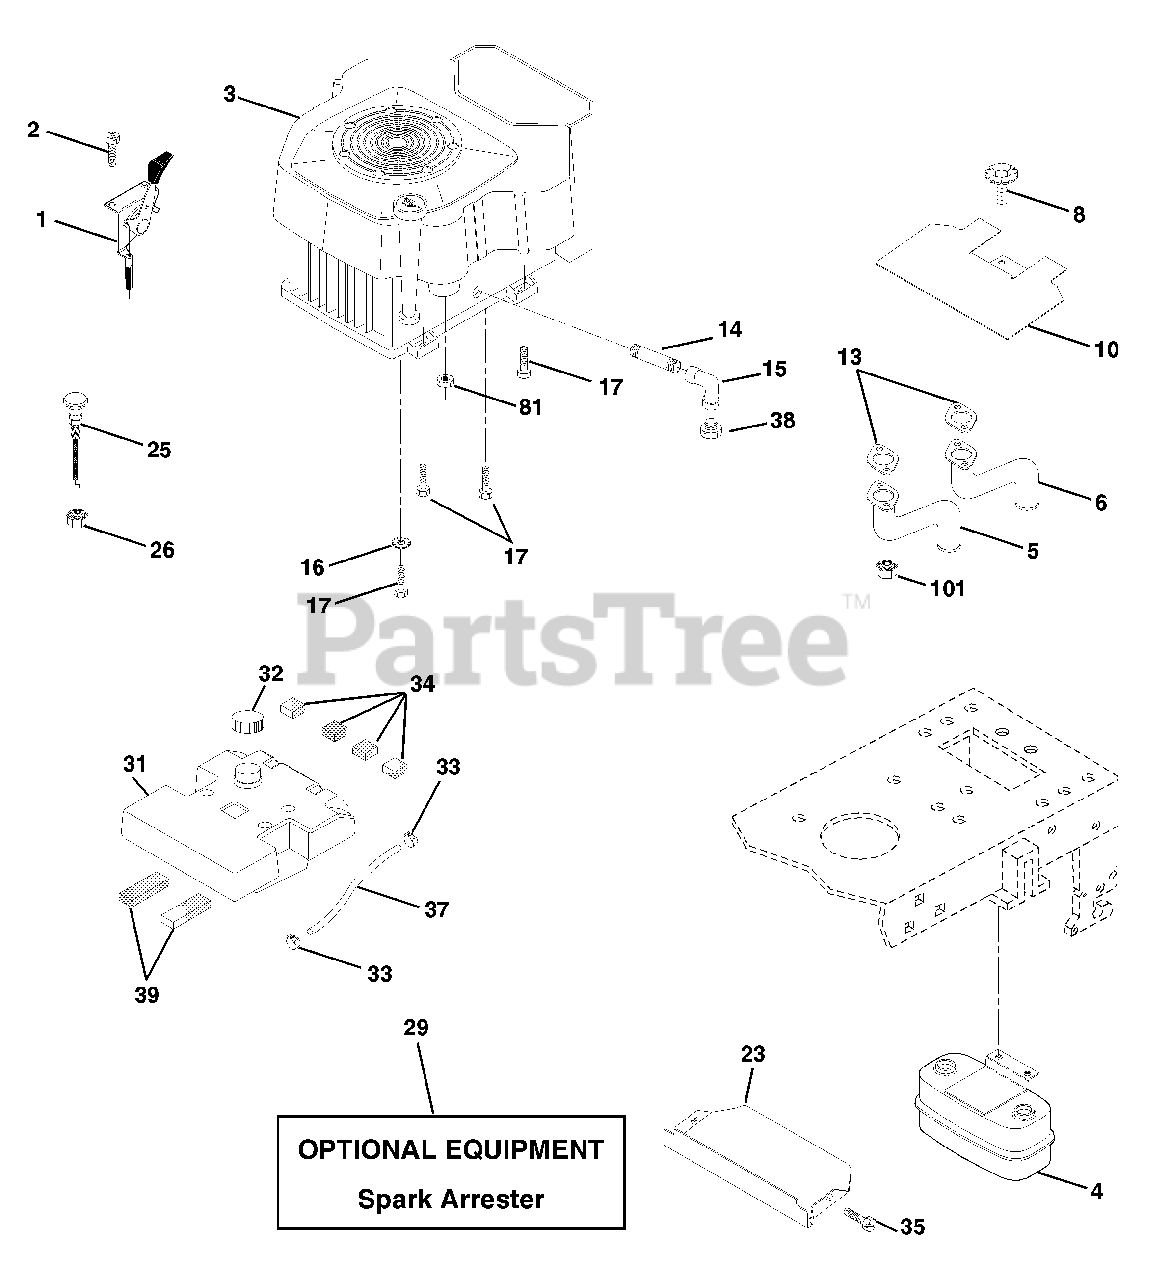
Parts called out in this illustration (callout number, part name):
1	Control Throt Flg 180 LH
2	Screw Hex Thd Cut 1/4-20x5/8 T
4	Muffler Asm Twin Lo-Tone
5	Pipe Exhaust CV18/20 LH
6	Pipe Exhaust CV18/20 RH
8	Bolt 5/16-18unc x 3/4 W/Sems
10	Shield Heat Muffler CV18/20
13	Gasket Kohler CV18-CV26
14	Nipple Pipe 3/8 Npt X 4-1/2"
15	Elbow Std 90 Degree 3/8-18 Npt
16	Washer Lock Ext Tooth 3/8
17	Screw Thdrol 3/8-16 x 1-1/2
23	Shield Browning
25	Choke Control 37"
26	Nut, Keps 3/8-24 Unf
29	Kit Spark Arrestor (Flat Scrn)
31	Tank Fuel 3 50 Rear
32	Cap Asm Fuel Top N/Lany Vented
33	Clamp Hose Blk
34	Pad, Spacer
35	Screw Thdrol 5/16-18 x 3/4
37	Line Fuel 7.5
38	Plug Oil Drain
39	Pad, Idler
81	Nut Flange 1/4-20 Starter Nut
101	Nut Flange M8-1.25 Non-Lk Zinc
